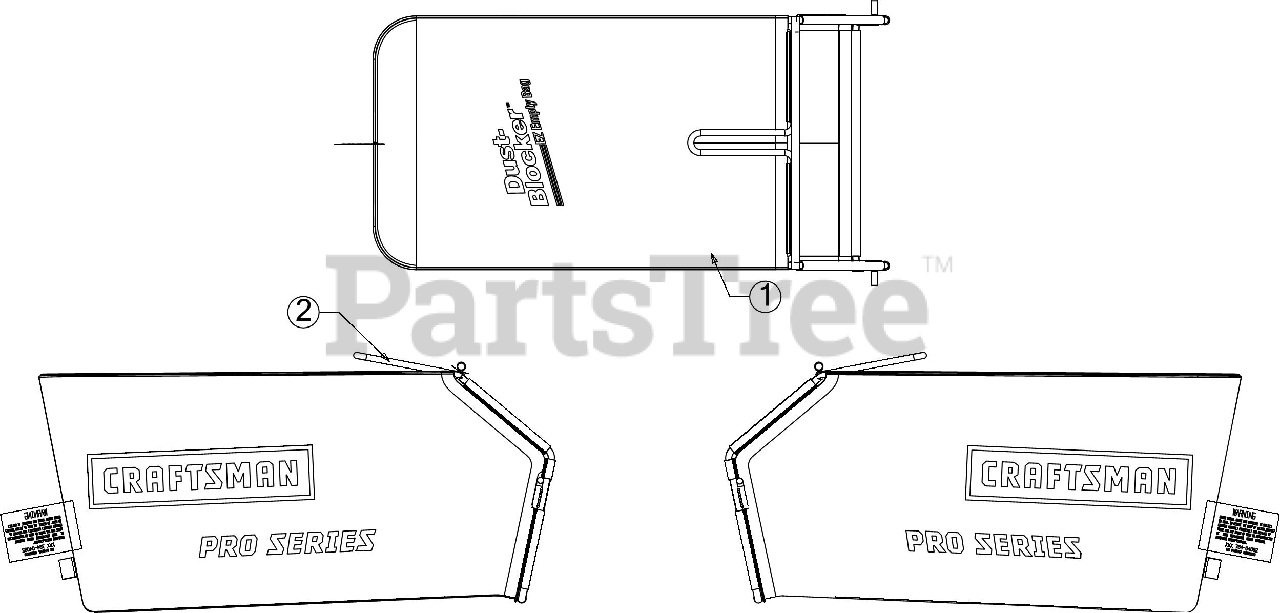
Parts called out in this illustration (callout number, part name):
1	GRASS BAG (CRAFTSMAN PRO)
1	GRASSBAG-21"
2	GRASSBAG FRAME ASSEMBLY
